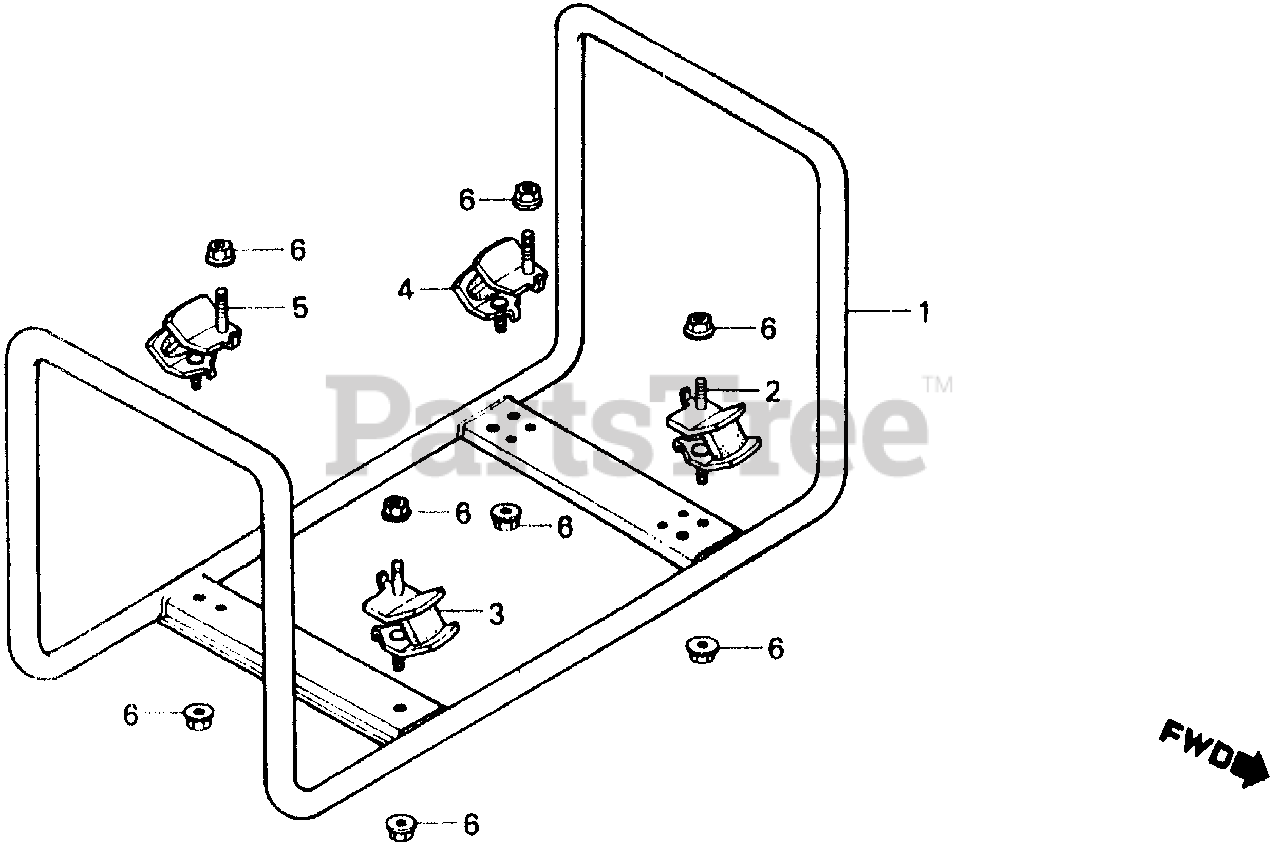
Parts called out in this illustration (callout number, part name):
2	RUBBER, FR. (LOWER)
3	RUBBER, FR. (LOWER)
4	RUBBER, RR. (LOWER)
5	RUBBER, RR. (LOWER)
6	NUT, FLANGE (8MM)
